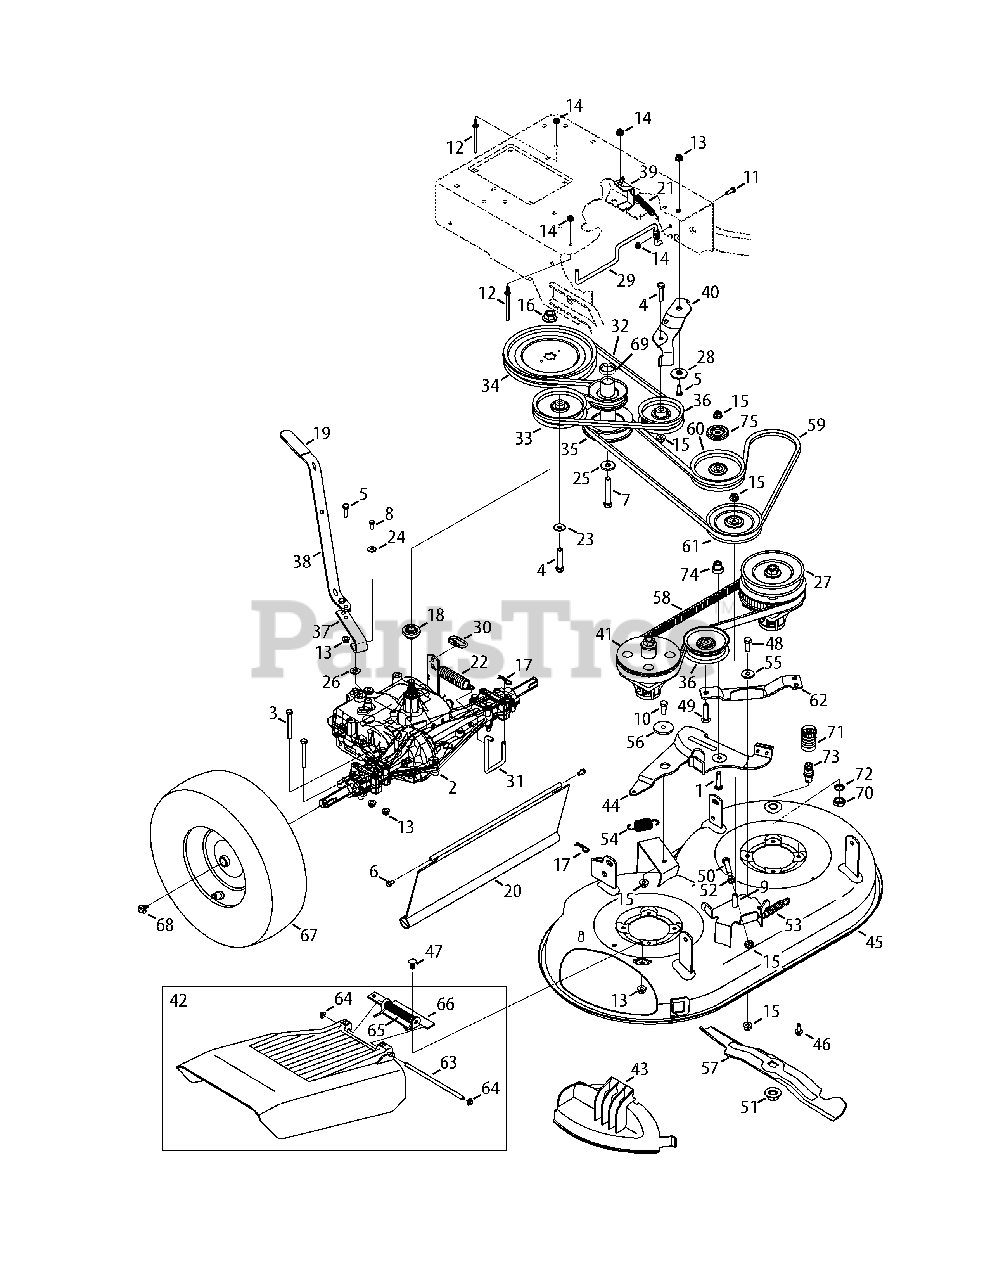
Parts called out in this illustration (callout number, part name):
1	Hex Head Cap Screw, 3/8-16 x 1.75
2	4 Speed Drive Assembly, Tecumseh
3	Hex Head Cap Screw, 5/16-18 x 2.75
4	Hex Head Cap Screw, 3/8-16 x 1.75
5	Hex Head Cap Screw, 5/16-18 x 1.00
6	Screw, 10-16 x 0.625
7	HHCS, 7/16-20 x 2.75
8	Hex Head Cap Screw, 1/4-28 x .625
9	Hex Head Cap Screw, 3/8-16 x 1.50
10	Hex Head Cap Screw, 3/8-16 x 1.25
11	Hex Head Cap Screw, 1/4-20 x .75
12	Belt Keeper, .25 DIA X 3.0
13	Flangelock Nut, 5/16-18
14	Flangelock Nut, 1/4-20
15	Flangelock Nut, 3/8-16
16	Flange Nut, 9/16-18
17	Click Pin, .092 x 1.64 LG
18	Spline Pulley Hub, 5/8
20	Trailshield, 8.35 x 19.17
21	Extension Spring, Wheel Drive
22	Extension Spring, Brake
23	Washer, Spring, .401 x .870 x .063
24	Washer, Bell, .265 x .75 x .062
25	Washer, Flat, .450 x 1.250 x .164
26	Washer, Flat, .39 x .87 x .06
27	Drive Spindle Assembly
28	Spacer, Shoulder, .5000 x .1475
29	Belt Keeper Rod
30	Coupling Link, 3/16
31	Brake Spring Mounting Rod
32	V Belt. 4L 64.2
33	Idler Pulley, 4.25 DIA
34	Flat Sheave, DIA 7.75
35	Engine Pulley, 3.20 x 4.35 DIA
36	Idler Pulley, 3.50 DIA
37	Lower Shaft Lever
38	Upper Shaft Lever
39	Belt Keeper, .375 x 2.00
41	Spacer Spindle Assembly
42	Chute Deflector Assembly
43	Mulch Cover
44	Idler Arm Assembly
45	Deck Assembly
46	Screw, 5/16-18 x .750
47	Bolt, Carriage, 5/16-18 x .750
48	Hex Head Cap Screw, 3/8-16 x 1.00
49	Screw, Carriage, 3/8-16 x 1.75
50	Hex Head Cap Screw, 3/8-16 x 2.00
51	Flange Nut, 5/8-18
52	Hex Nut, 3/8-16
53	Extension Spring, Timing Belt
54	Extension Spring, Deck Brake
55	Shoulder Spacer, .625 ID x .169
56	Shoulder Spacer, .8840 x .190
57	2 in 1 Blade
58	Timing Belt, .315 x .787
59	Aramid V Belt, 72.2
60	Idler Pulley, 4.25" DIA
61	Idler Pulley, V-Type, 5.0 DIA
62	Timing Idler Bracket
63	Deflector Pin
64	Push Cap
65	Deflector Torsion Spring
66	Deflector Hinge Bracket
67	Wheel, 16 x 4 x 8
68	Screw, 5/16-24 x .750
69	Spacer, 1.0 x 1.28 x .31 (420CC)
70	Nut, Hex, M16-1.5
71	Water Nozzle Adaptor
72	Washer, Lock, 5/8
73	Deck Water Nozzle
74	Shoulder Spacer
75	Pulley Cap
